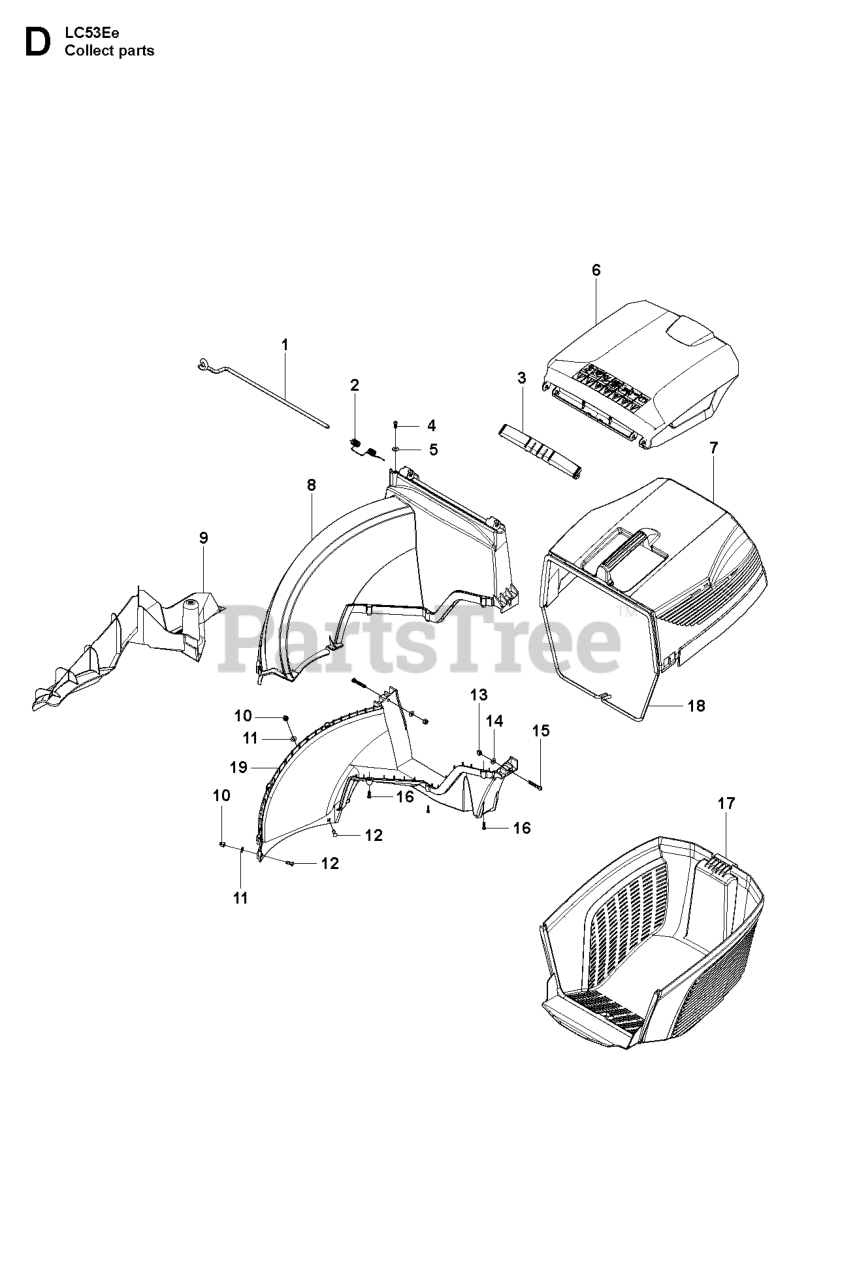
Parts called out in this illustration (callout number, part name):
1	AXLE HATCH REAR DISCHARGE
2	SPRING SAFETY FLAP A009
4	SCREW ITXPANT T50X16 ZN/FE (A
6	HATCH REAR DISCHARGE
7	GRASSBAG UPPER
16	SCREW ITXPANT T50X16 ZN/FE (A
17	GRASSBAG LOWER
